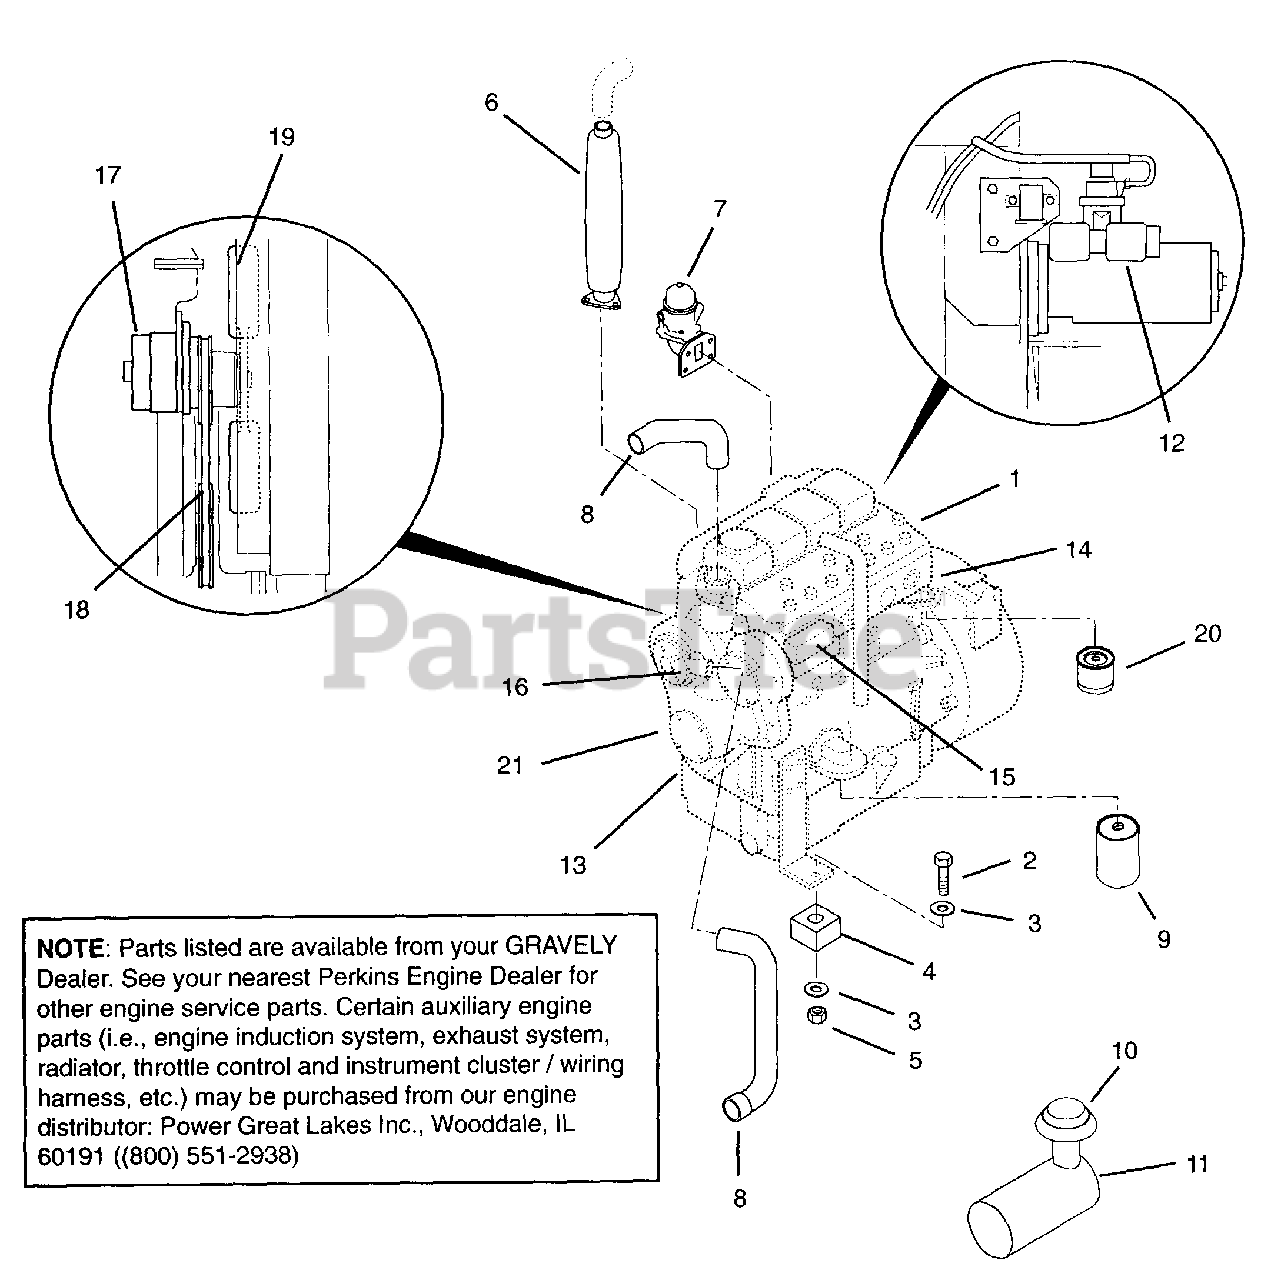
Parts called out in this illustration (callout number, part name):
1	Engine-Perkins AR70427 86 HP Diesel
1	Engine-Perkins AR70428 86 HP Diesel
1	Engine-Perkins AK70453 110 HP Diesel
2	Bolt-Hex .75-10 x 3.00 Grade 5
3	Washer-Flat-Steel .813 x 2.000 x .148
4	Engine Base Spacer
5	Nut-Locking-Center .75-10
6	Muffler
7	Pump-Lift
8	Hose-Radiator-Top & Bottom
9	Filter-Oil
9	Filter Oil
10	Filter-Air-Primary
11	Filter-Air-Secondary
13	Gasket Set-Bottom
13	Gasket Set Bottom
14	Gasket Set-Top
15	Pump-Injection
16	Pump-Water
17	Alternator
19	Fan
20	Element-Fuel Filter
21	Pump-Oil
